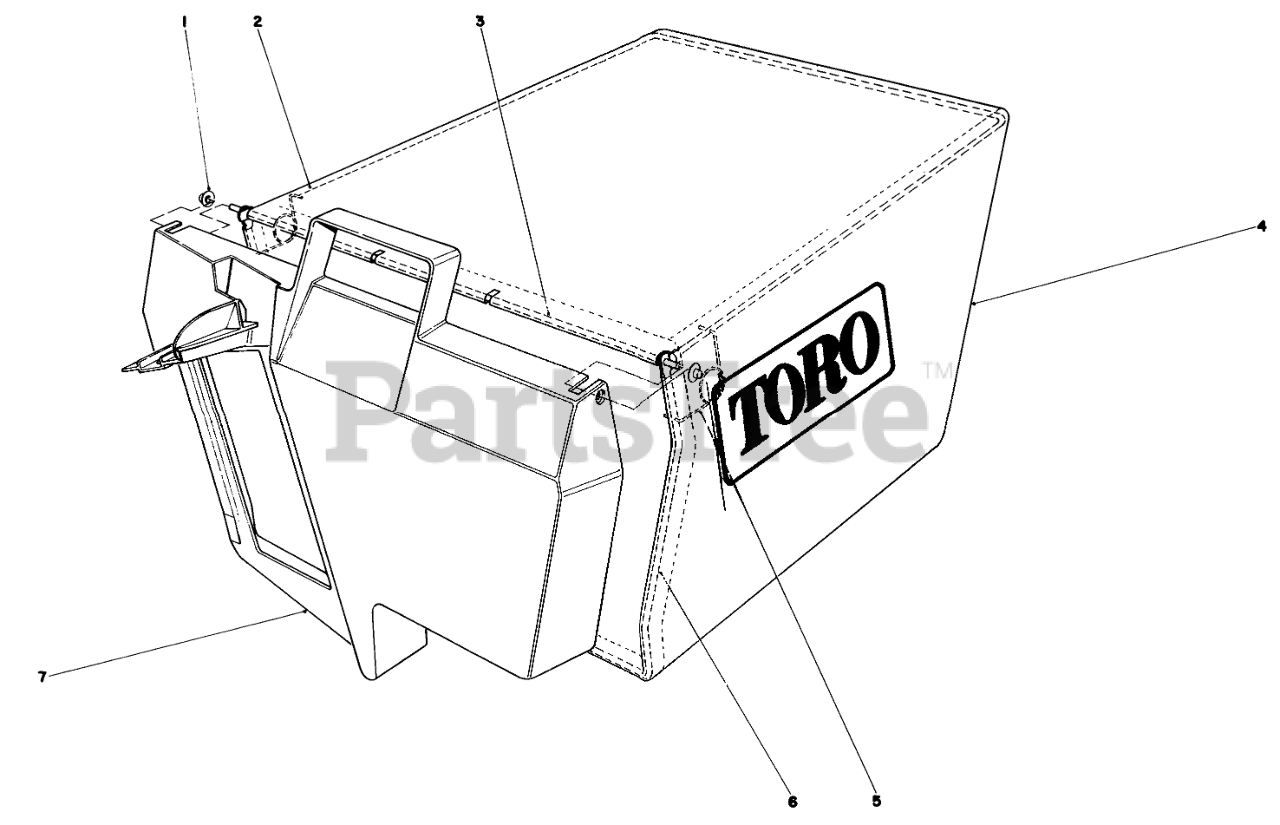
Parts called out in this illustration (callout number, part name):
1	NUT-PUSH
2	Bag Frame Upper
3	HingeBag Door
4	Bag
5	SPRING
6	BAG FRAME
7	Door Grass Bag
